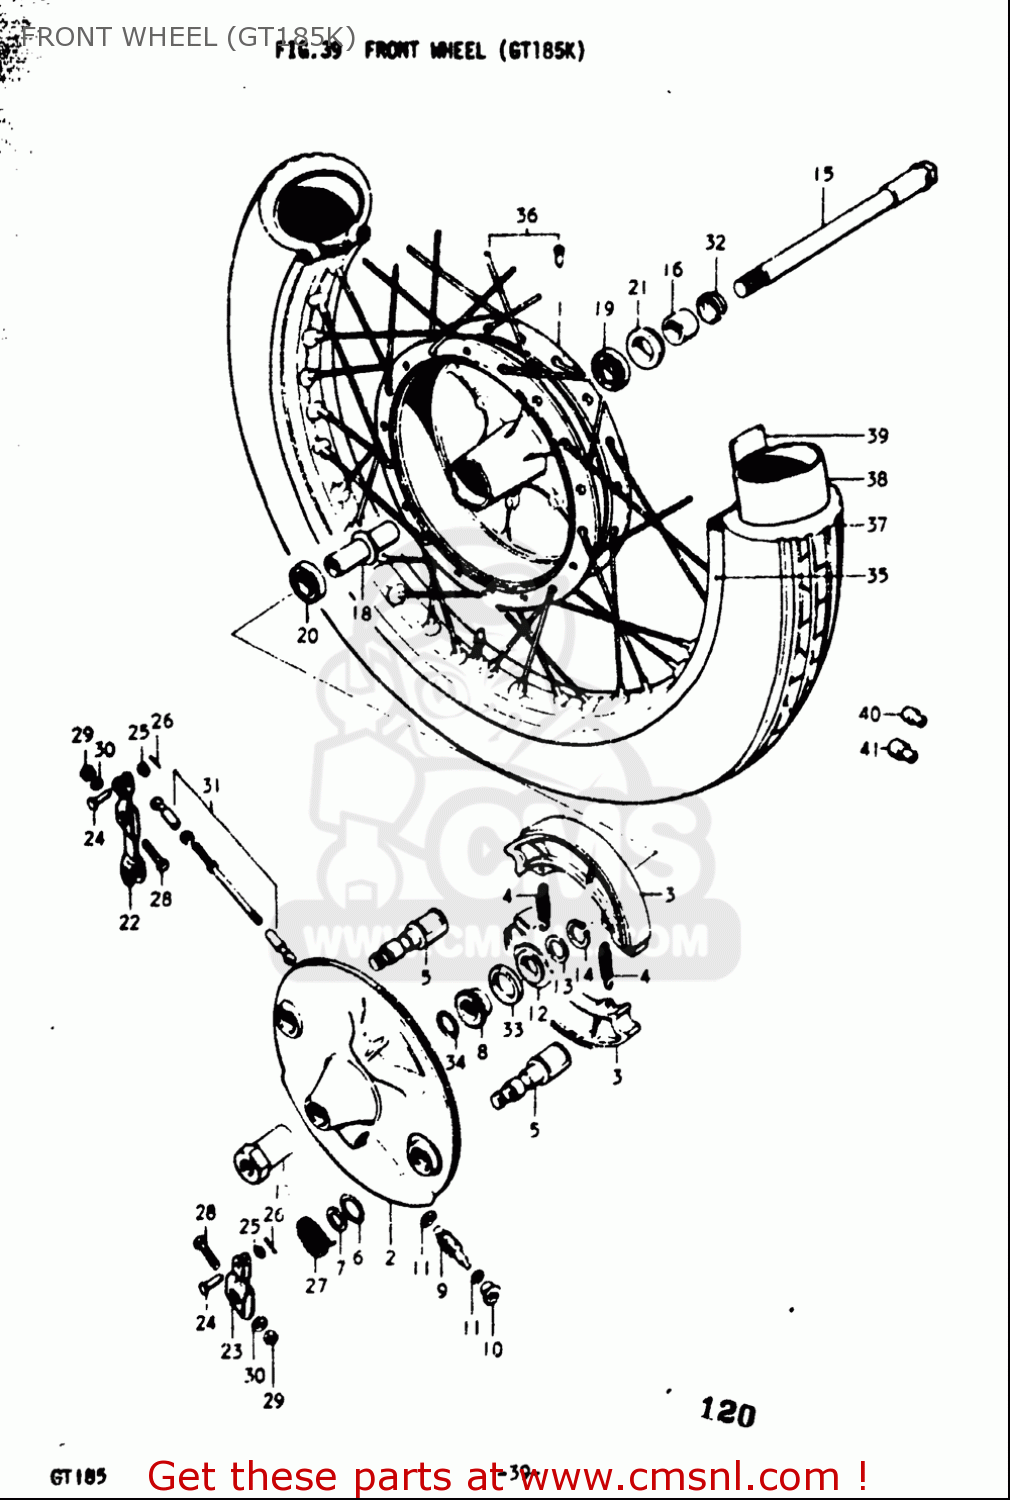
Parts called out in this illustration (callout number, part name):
3	SHOE,BRAKE
4	SPRING,BRAKE SHOE
5	CAM,RR BRAKE
6	O RING(D:2.4,ID:14.8)
7	WASHER(15.5X24X1.6)
8	GEAR,SPEEDOMETER
9	PINION,SPEEDOMETER
10	BUSHING,SPEEDOMETER PINION
11	WASHER(5.1X9X0.4)
12	DRIVER,SPEEDOMETER GEAR
13	WASHER(22.5X27X1)
14	CIRCLIP
16	SPACER
19	BEARING
20	BEARING
25	WASHER
26	PIN 12X10
27	SPRING
28	BOLT(6X31)
29	NUT
30	WASHER
33	SEAL,OIL(26X38X4)
34	SEAL,OIL(6X10X3)
35	RIM,FR WHEEL 1.60X18
37	TIRE,FR(2.75-18)
38	TUBE ASSY,WHEEL INNER
39	PROTECTOR,INNER TUBE
40	BALANCER,WHEEL (B)
41	BALANCER,WHEEL (30G)
